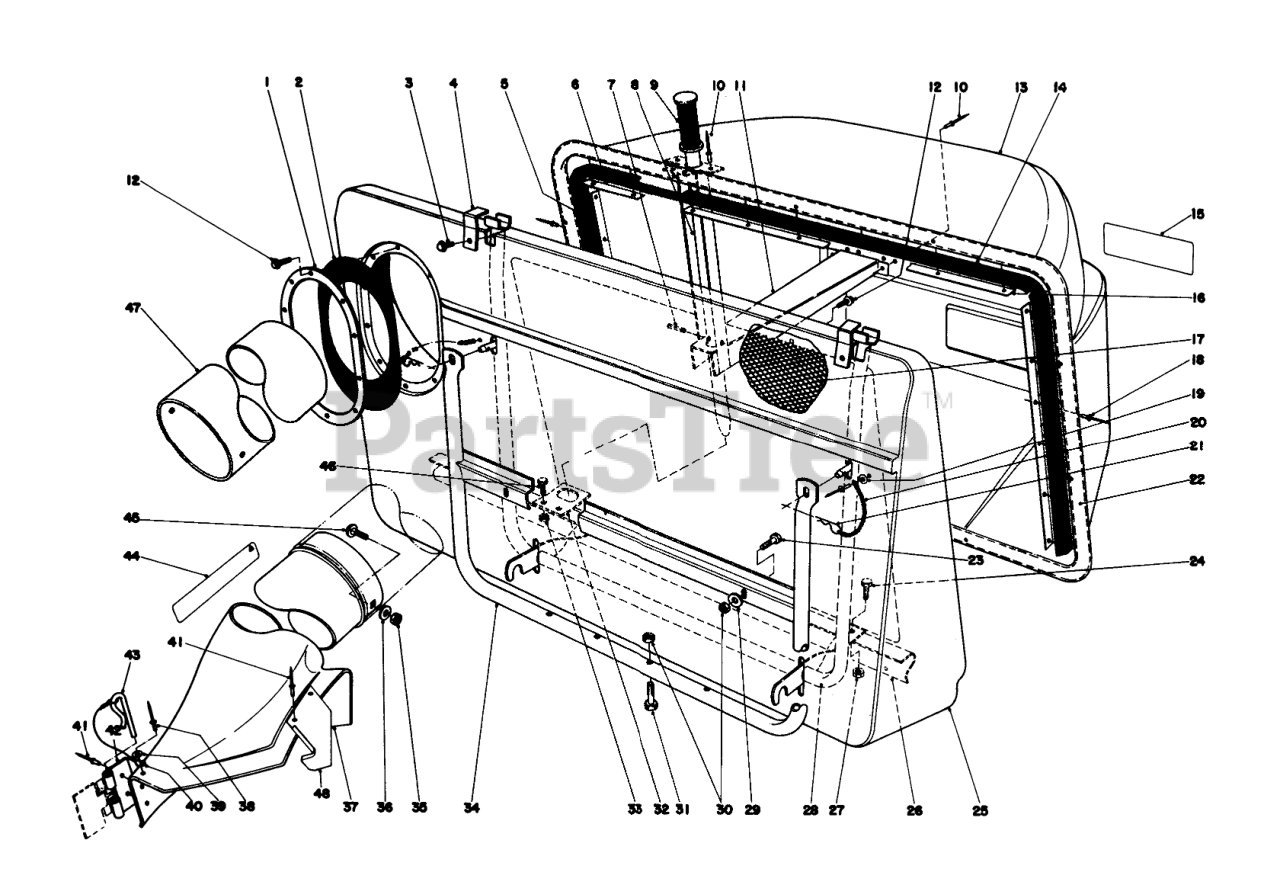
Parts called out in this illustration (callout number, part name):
1	RING-RETAINING
2	RING-RETAINER, RUBBER
3	Hex Hd. Tap Screw
4	RETNR PIVOT BRKT
5	RH BAG SEAL
6	RETNR TOP EXT.
7	PIN-ROLL
8	DUMP HANDLE ASM
11	Support-Bag Dump Handle
12	SCREW-HWHTF
13	REAR GRASS BASKET
14	Seal-Bag LH.
15	EASY EMPTY BAG DECAL
16	BAG RETNR EXT.
17	Screen Bag
18	Rivet-Pop
19	WASHER
20	10 LINK CHAIN W/O HOOK
21	PIN-HAIR
22	BAG SUPT ASM FRM
23	SCREW-HH
24	SCREW-HH
25	Bag Front
26	FRAME SUPT BRKT B
27	NUT-LOCK, CONE
28	Bag Frame
29	WASHER-PLAIN
30	NUT-LOCK, CONE
31	SCREW-HH
32	Hanger-Frame Lower
33	NUT-LOCK, CONE
34	BAG SUPPORT WA
35	NUT-KEPS
36	WASHER-FLAT
37	Chute Assembly (Incl. Ref. #38-44 & 48)
38	RIVET-BLIND
39	WASHER-PLAIN
40	LANYARD
41	RIVET-BLIND
42	BRACKET-MOUNTING, CHUTE
43	PIN-LOCKING, CHUTE
44	Decal-Chute
45	Carriage Bolt
46	SCREW-HH
47	Duct
48	CHUTE SUPT BRKT
